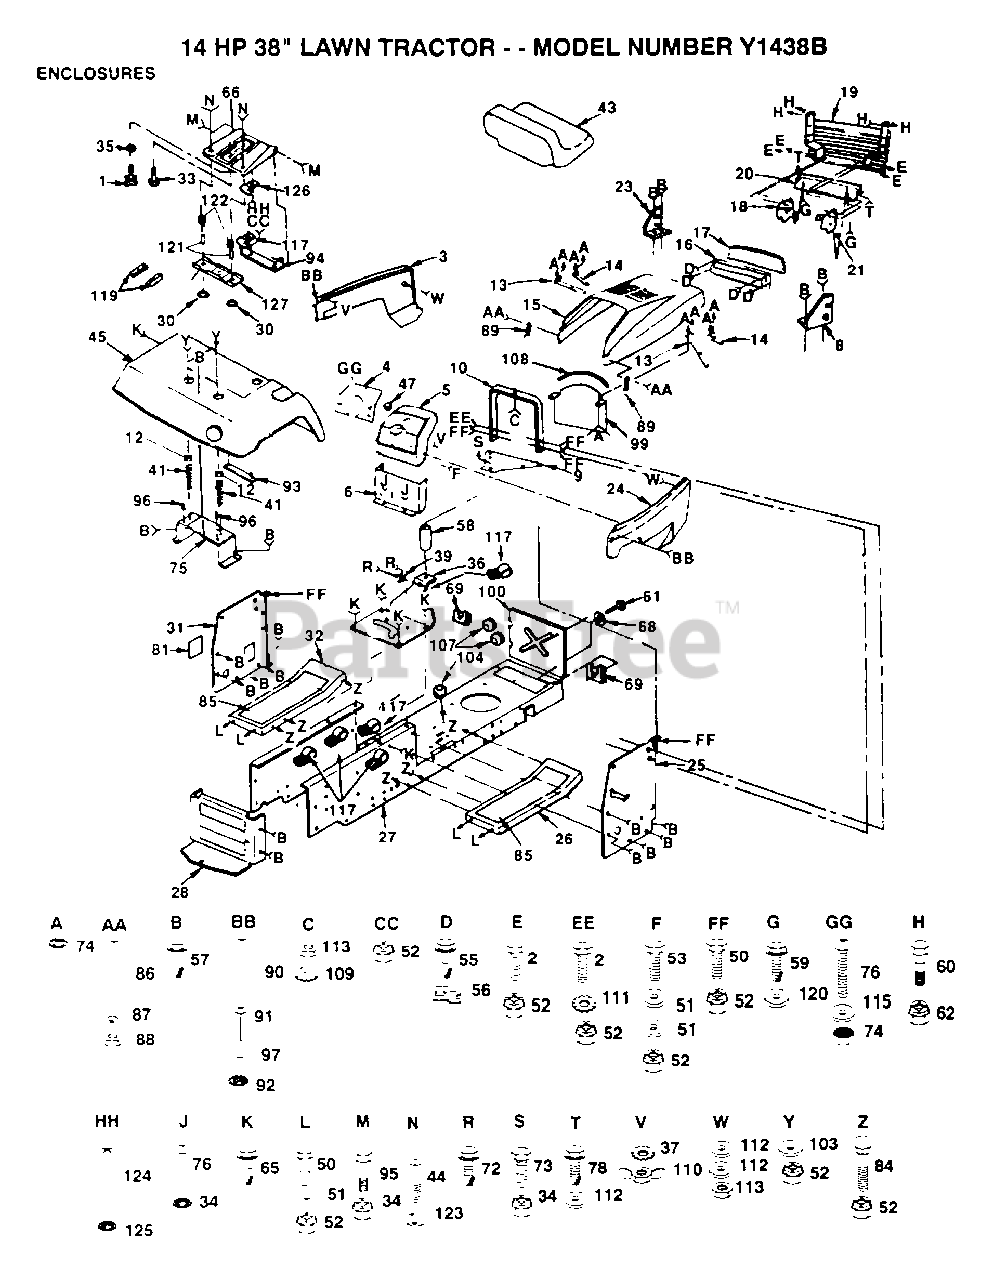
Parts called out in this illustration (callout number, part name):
1	"KNOB 1/2"" YT"
2	BOLT
6	DASH ASSY LT
8	SUPPORT RH YTH
10	SUPPORT ASS'Y
12	CAP SPRING
17	LENS LT
18	SUPPORT LH YTH
20	"STRAP,GRILL "
21	SUPPORT RH YTH
23	SUPPORT LH YTH
27	CHASSIS
28	DRAWBAR LT/YT
30	BUSHING
31	PANEL DASH LH
33	"BOLT,SHOULDER"
35	WASHER
37	LOCKWASHER GT
41	SPRING COMPRESSIO
44	BOLT
47	PLUG-DASH T
51	WASHER
56	"""J"" FASTENER LT"
57	SCREW
58	SPACER
59	SCREW
61	STUD.1/4.TURN
65	SCREW LT
68	RETAINER LT
69	RECEPTACLE LT
73	BOLT
76	SCREW
78	SCREW HEX CRT
81	COVER ACCESS
84	BOLT
85	"PAD,FOOTREST"
86	SCREW
87	LOCKWASHER
88	WELDNUT
89	HOOD LATCH T
90	SCREW
91	SPACER LT
96	NUT-PUSH YT
97	WASHER
99	BAFFLE
103	WASHER
104	SNAP BUSHING T
111	LOCKWASHER
112	WASHER PM
115	WASHER
117	CLIP T
119	STRIP FORM
120	WASHER
121	SPACER SPLIT
122	SPRING
125	"NUT,KEPS"
127	BRKT SWITCH
